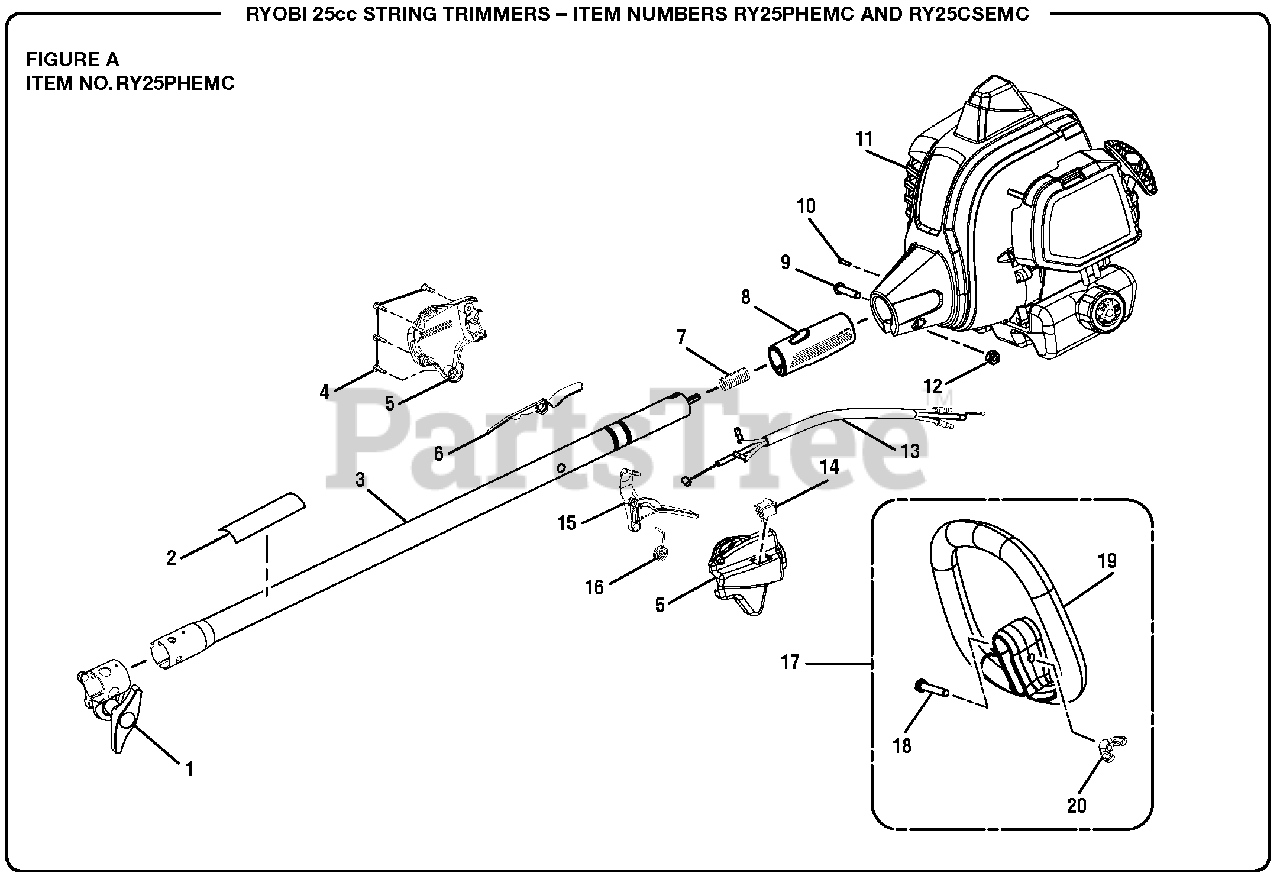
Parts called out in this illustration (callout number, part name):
1	Boom Clamp Assembly
2	Warning Icon Label
3	Upper Boom Assembly
4	Screw (M4 x 20 mm, T20 Torx Hd. S.T.)
5	Control Handle Assembly
6	Trigger Lock
7	Compression Spring
8	Rear Handle Grip
9	Screw (M6 x 30 mm, T27 Torx Button Hd.)
10	Screw (M4 x 8 mm, T20 Torx Pan Hd. S.T.)
11	Powerhead Assembly w/Labels
12	Hex Nut (M6 x 1)
13	Throttle Cable and Wire Assembly
14	On/Stop Switch
15	Trigger
16	Trigger Spring
17	Front Handle Assembly
18	Screw (1/4-20 x 40 mm, Cap Hex Hd.)
19	Front Handle
20	Wing Nut (1/4-20)
